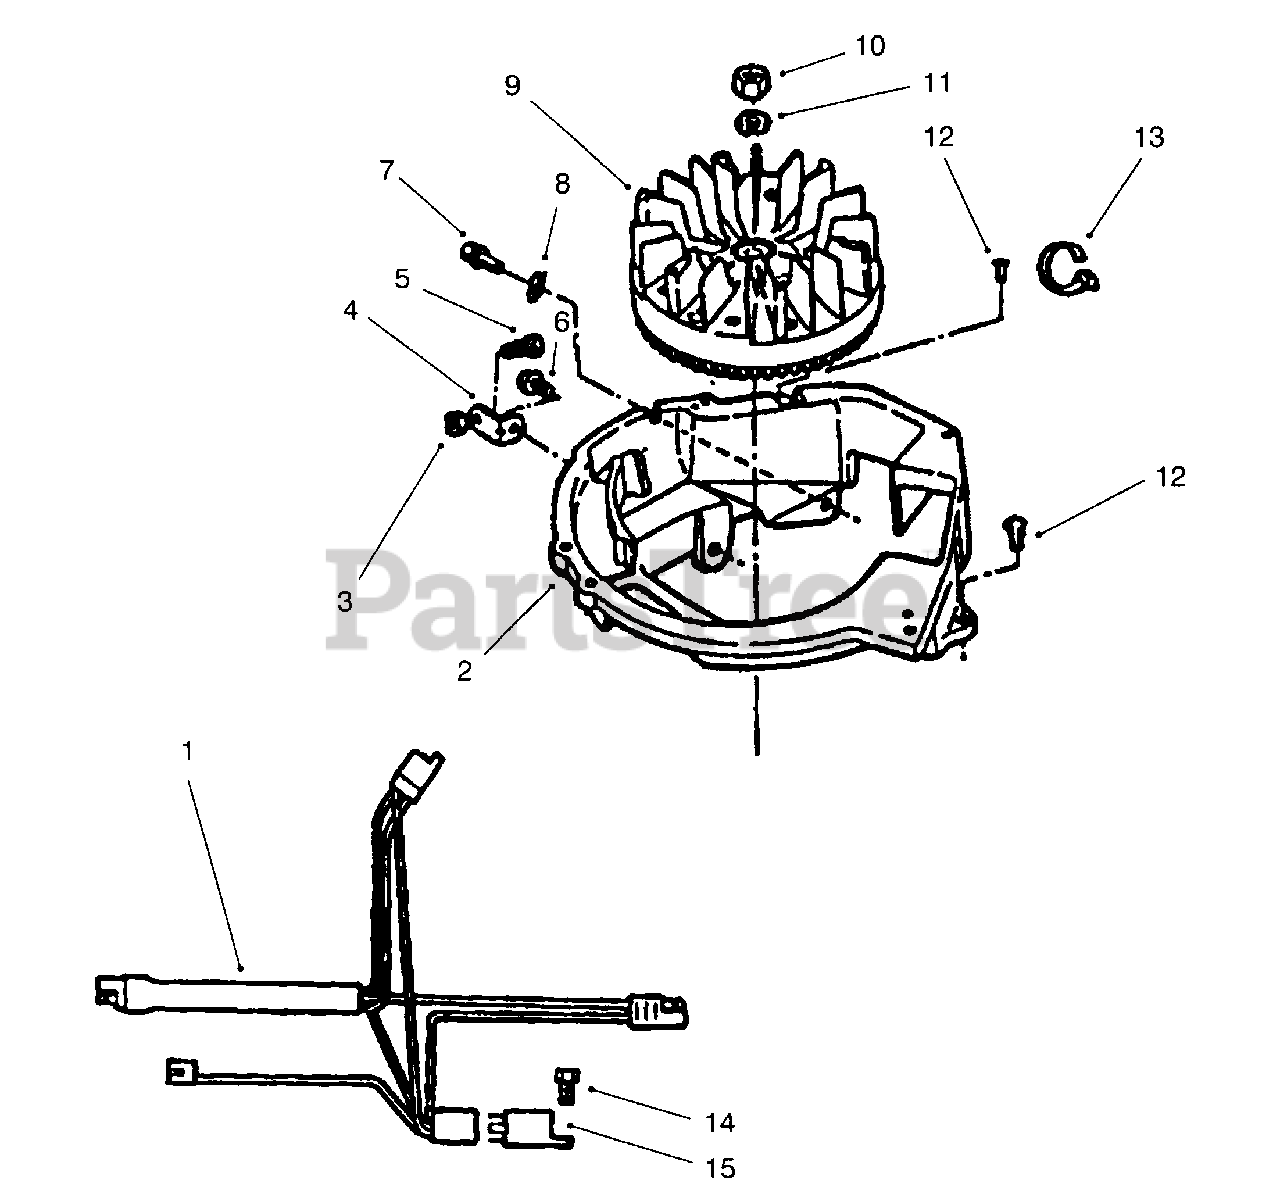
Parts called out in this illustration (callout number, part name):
1	Harness-Wire
2	Base-Shroud
4	Brace-Alternator
9	Flywheel
10	Nut-Flywheel
11	Washer-Lock
13	Strap-Tie
